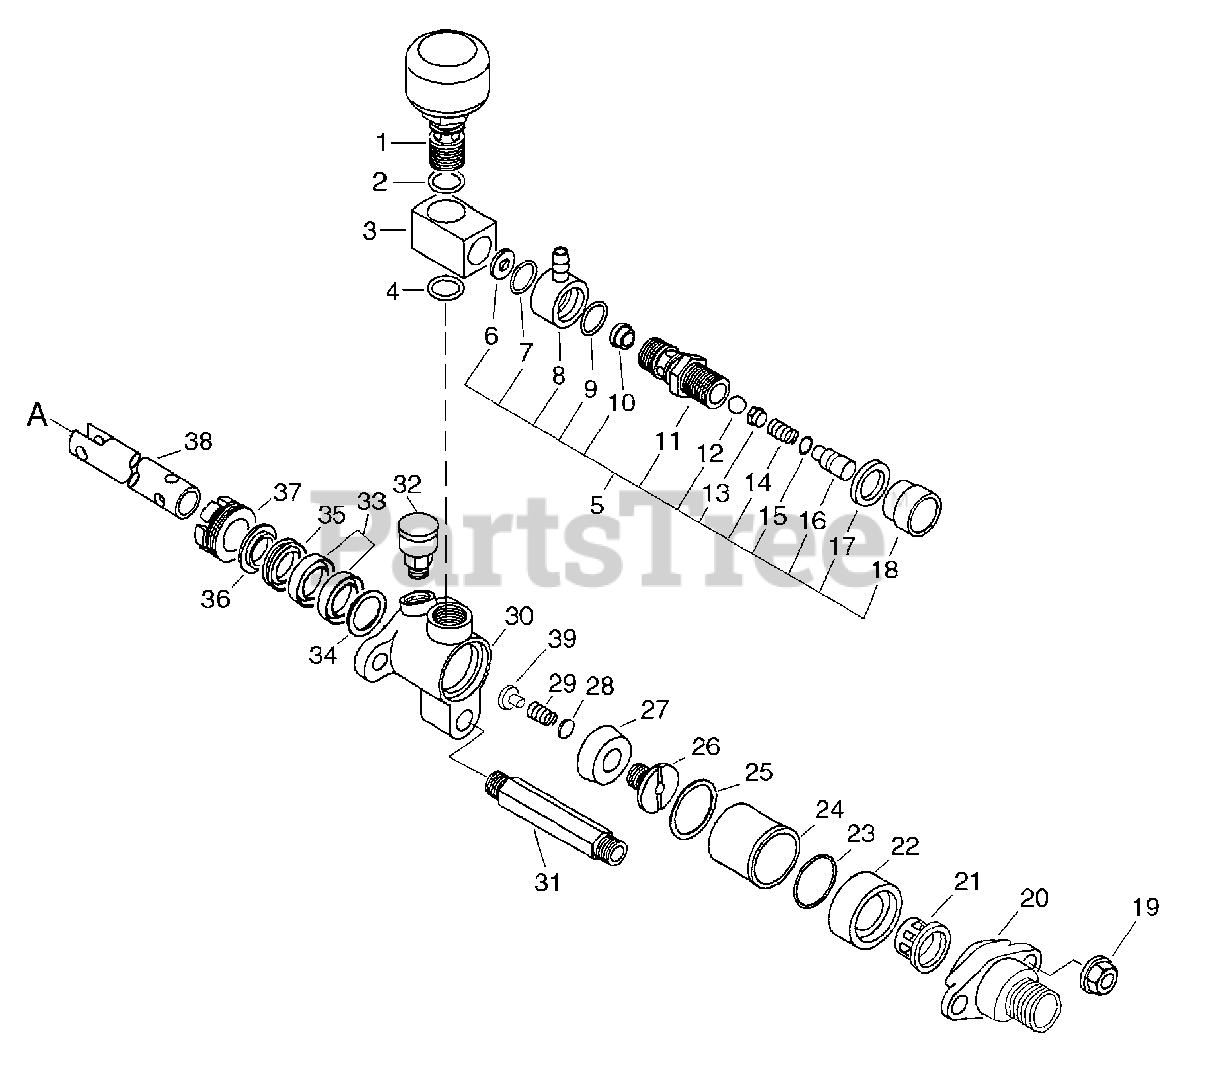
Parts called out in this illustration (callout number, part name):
1	Air Chamber
2	O-Ring 12.5
3	Connector
4	O-Ring P-16
5	Regulator Asy
7	O-Ring P-16
8	Valve Casing
9	O-Ring 12.5
10	Seat,Valve
11	Spring Casing
12	Spring Seat
13	Ball Valve
14	Pressure Spring
16	Spring Seat
17	Lock Nut
18	Regulator Cap
20	Intake Pipe
21	Valve Assy
22	Valve Casing
26	Valve Seat
27	Piston Packing
28	Disk,Valve
29	Valve Spring
30	Cylinder
32	Grease Cup
33	V-Packing Set
35	Grease Ring
36	L-Packing
37	Nut Gland
38	Plunger W/Springseat
39	Spring Seat
